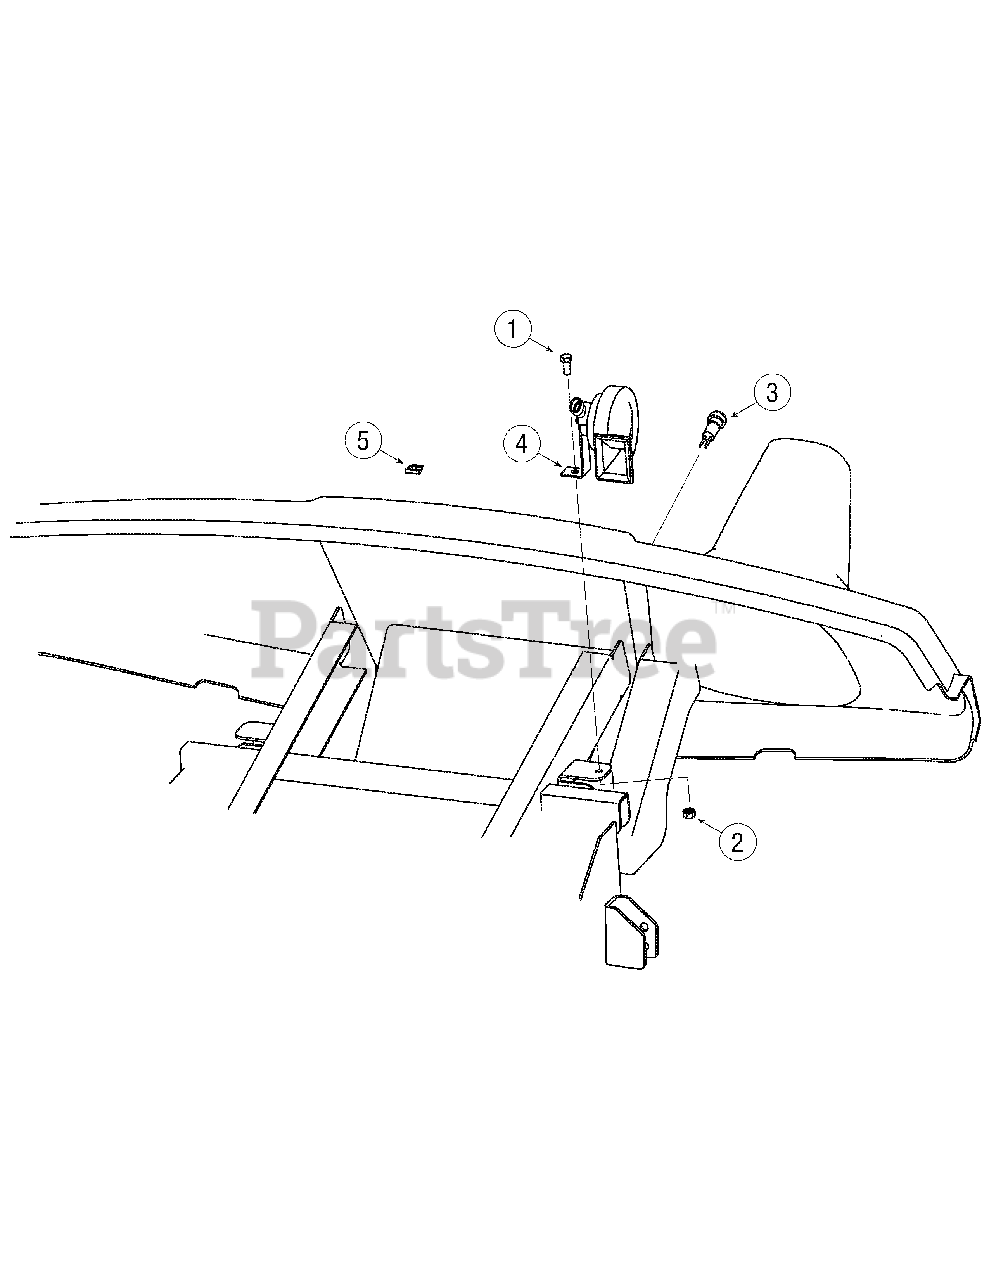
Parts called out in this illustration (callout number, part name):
1	Hhcs, 5/16-18 x .75
2	Nut, Sems, 5/16-18
3	Switch, Horn
5	Fuse, 7.5 amp
